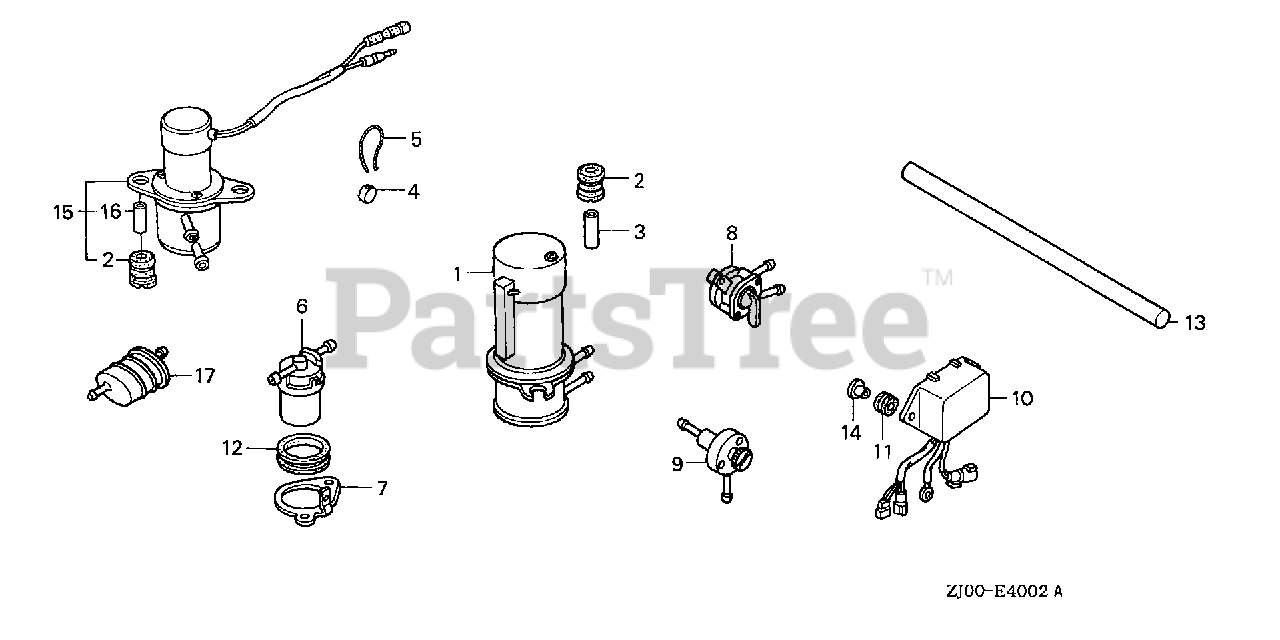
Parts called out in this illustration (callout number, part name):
2	RUBBER, FUEL PUMP MOUNTING
15	PUMP ASSY., FUEL (MSDS)
16	COLLAR, FUEL PUMP DISTANCE
17	FILTER, FUEL
